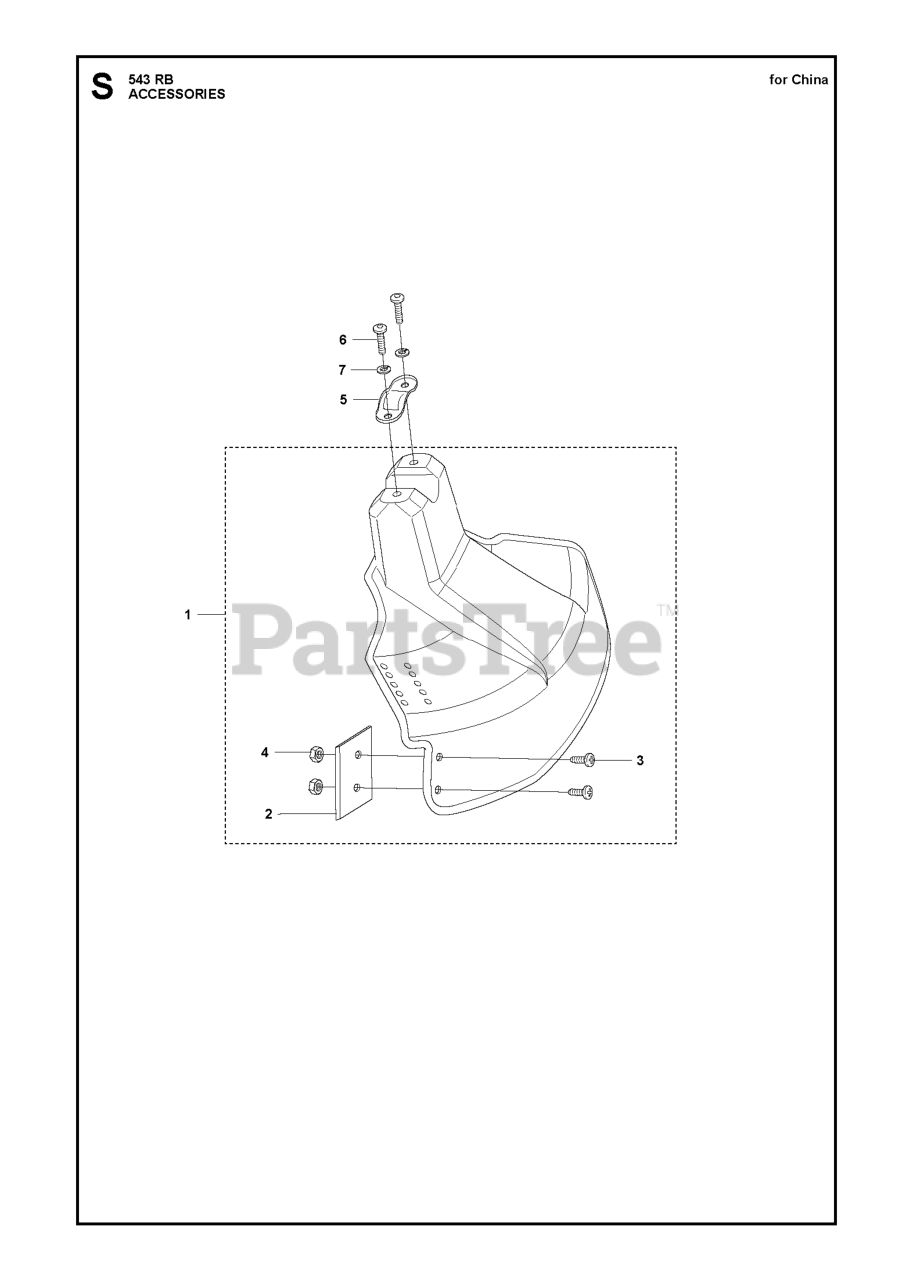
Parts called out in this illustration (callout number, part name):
3	SCREW
4	NUT
5	CLAMP
6	BOLT
7	WASHER
